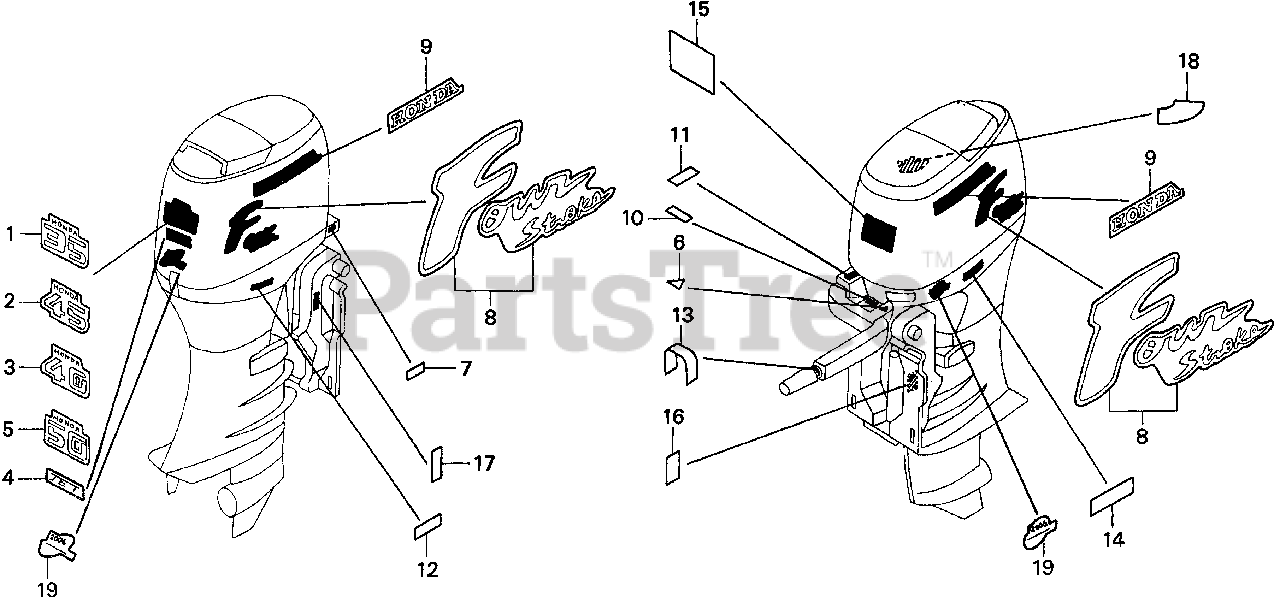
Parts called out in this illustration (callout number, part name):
5	MARK, RR. (50)
8	MARK, SIDE
9	MARK, SIDE STRIPE
10	LABEL, SPECIFICATION (NMMA)
12	LABEL, OIL CAUTION (ENGLISH)
14	LABEL, STORING CAUTION (ENGLISH)
15	LABEL, CAUTION OPERATOR (ENGLISH)
16	LABEL, ASSIST TILT CAUTION (ENGLISH)
17	MARK, ASSIST LEVER (E)
18	MARK, EMERGENCY START (ENGLISH)
19	MARK, ENVIRONMENT (EPA 2006)
